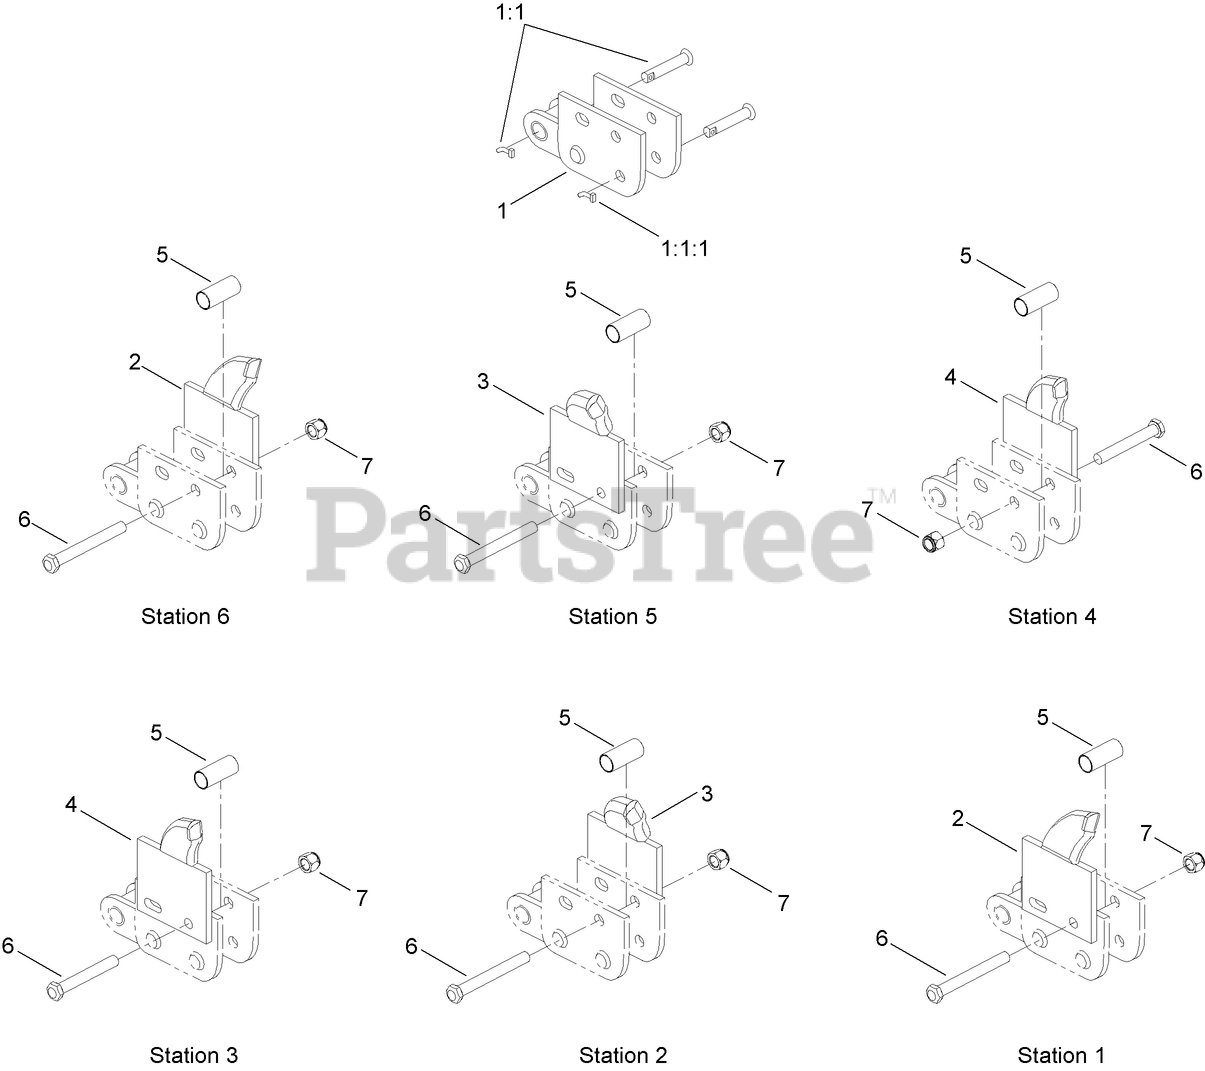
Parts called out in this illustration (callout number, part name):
1	CHAIN REPAIR LINK ASM
1:1	NOTCHED PIN AND KEEPER ASM
1:1:1	PIN-KEEPER
2	TOOTH-TERMINATOR, LH
3	TOOTH-TERMINATOR, RH
4	TOOTH-TERMINATOR, STRAIGHT
5	SPACER-TUBE, OUTSIDE MOUNT
6	BOLT-HH
7	NUT-LOCK
